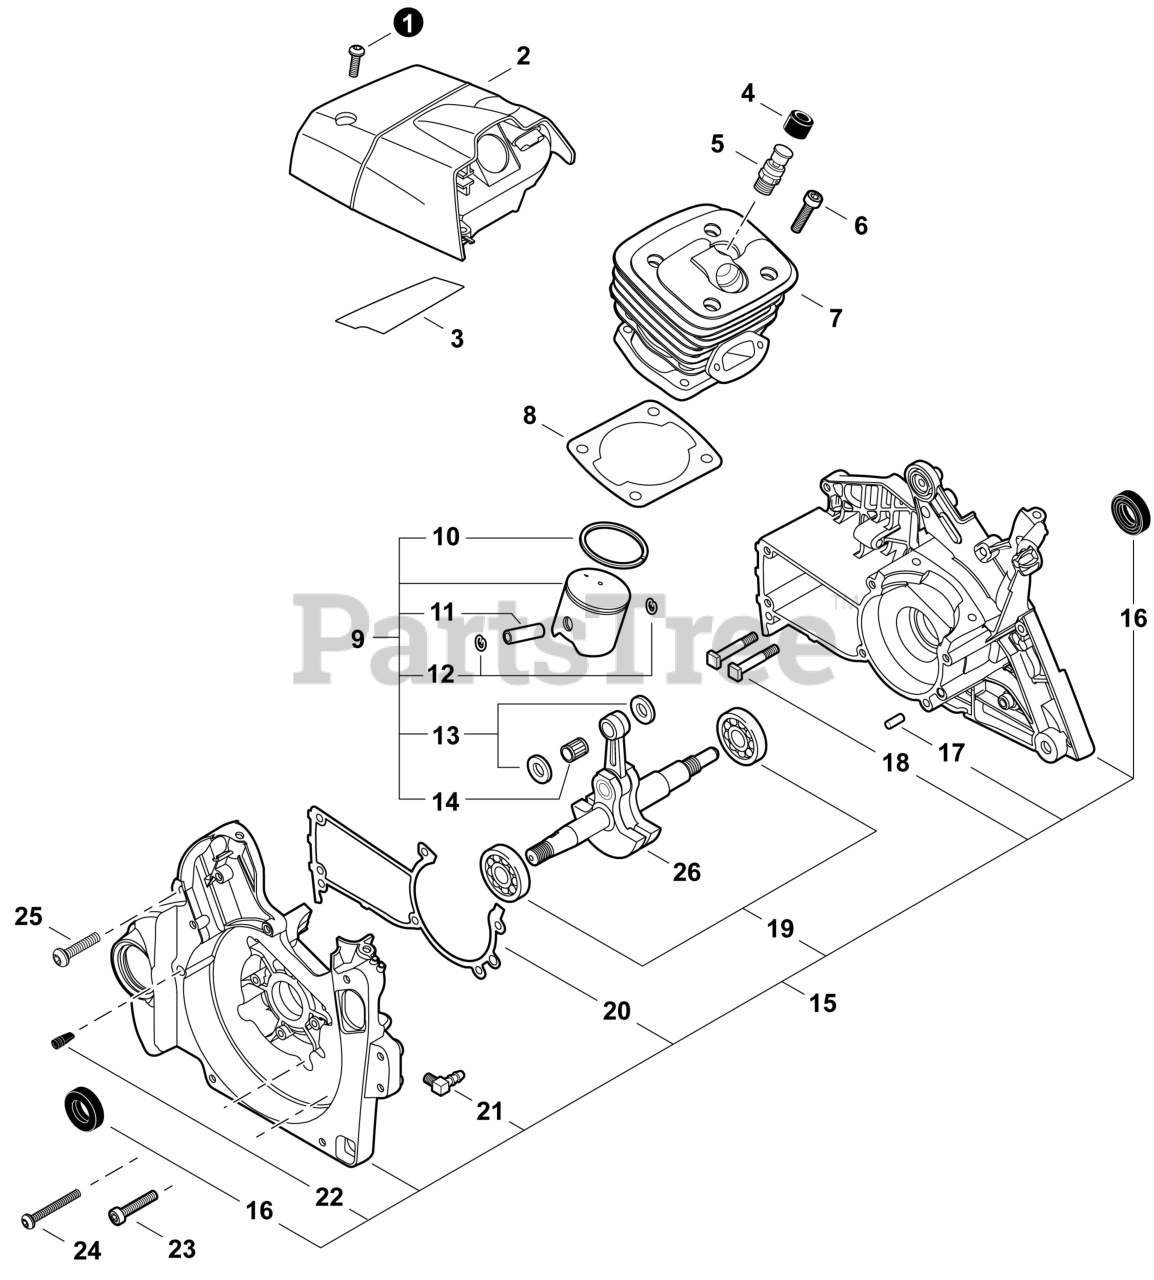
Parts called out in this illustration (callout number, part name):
1	BOLT, TORX 5x16
2	COVER, ENGINE
3	SHIELD, HEAT 75x32x0.15
4	COVER, DUST
5	VALVE ASSY, DECOMPRESSION
6	BOLT, TORX 5x25
7	CYLINDER
8	GASKET, CYLINDER
9	PISTON KIT
10	RING, PISTON
11	PIN, PISTON
12	RING, SNAP 11
13	WASHER, THRUST
14	BEARING, NEEDLE 11
15	CRANKCASE KIT
16	SEAL, OIL 15
17	PIN, LOCATING 5x10
18	BOLT, STUD M8x1.25x34.5
19	BEARING, BALL 6202
20	GASKET, CRANKCASE
21	CONNECTOR, PIPE
22	VENT ASSY
23	BOLT, TORX 5x25
24	BOLT, TORX 5x35
25	BOLT, TORX 5x20
26	CRANKSHAFT ASSY
